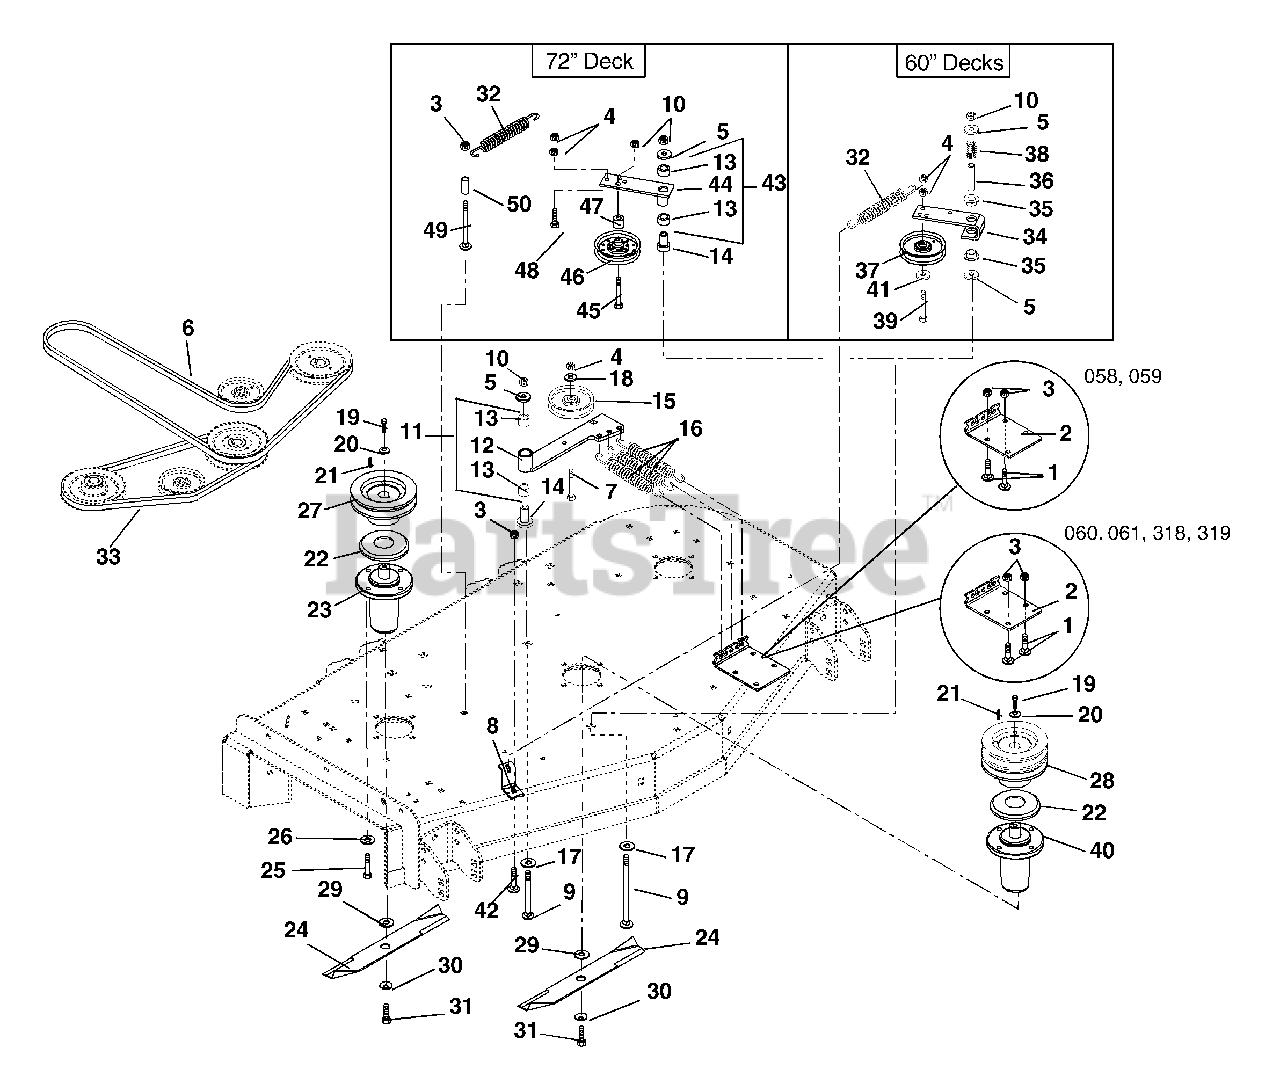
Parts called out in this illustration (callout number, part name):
1	Bolt, Round Head Square Neck .38-16 x .75 Grade 5
2	Bracket, Spring
3	Nut, Locking Top Flange .38-16 (058, 060, 318, 319)
3	Nut, Locking Top Flange .38-16 (059, 061)
4	Nut, Locking Center .38-16
5	Washer, Flat Steel .531 x 1.25 x .10 (058, 060, 318, 319)
5	Washer, Flat Steel .531 x 1.25 x .10 (059, 061)
6	V-BELT, HB-WRAPPED (058, 060, 318, 319)
6	V-Belt, B-Section 58.25 x .625 (059, 061)
7	Bolt-Round Head Square Neck .38-16 x 2.75 Grade 5
8	Anchor, Spring
9	Bolt, Round Head Square Neck .50-13 x 3.50 Grade 5
10	Nut, Locking Top Flange .50-13 (058, 060, 318, 319)
10	Nut, Locking Top Flange .50-13 (059, 061)
11	Assembly-Deck Idler Pivot Arm (Contains Items 12 & 13)
12	Weldment, Deck Idler Pivot Arm
13	Bearing, 1.00 x 1.12 x .75
14	Bearing, Pedestal Powdered Metal (058, 060, 318, 319)
14	Bearing, Pedestal Powdered Metal (059, 061)
15	Idler, Flat 4.00 x .38 (2.32W)
16	Spring, Extension
17	Washer, Flat Steel .755 x 1.375 x .062
18	Washer, Flat Steel .375 x 1.125 x .065
19	Bolt, Hex .38-16 x 1.00 Grade 8
20	Washer, Cupped Serrated .375
21	Key, Square .25 x .25 x 1.00
22	Slinger, Dust
23	Assembly, Maintenance Free Spindle
24	Blade 60" Mower CE (318, 319)
24	Blade, Mower 60" Mulch (058, 060, 318, 319)
24	Blade, Mower-72" (24.50" LG) (059, 061)
24	Blade, Mower (058, 060)
24	Blade, Mower 72" Mulch (059, 061)
25	Bolt, Hex .38-16 x 1.00 Grade 5
26	Washer, Locking .38 x .094 Regular
27	Weldment, Spindle Sheave 6.00 (058, 060, 318, 319)
27	Weldment, Spindle Sheave (059, 061)
28	Sheave, Double (6.25) (058, 060, 318, 319)
28	Sheave, Double (7.25) (059, 061)
29	Washer, Flat .64 x 1.81 x .25
30	Washer, Bellville .63 x 1.625 x .14
31	Bolt, Hex .62-18 x 1.75 Grade 8
32	Spring, Extension (058, 060, 318, 319)
33	V-Belt B-Section 23.94 x .625 (058, 060, 318, 319)
33	V-Belt 5L-Section 49.97 x .672 (059, 061)
34	Arm, Idler Pivot (058, 060, 318, 319)
35	Bushing, Flange .762 x 1.00 x .58 x 1.48 Nylon (058, 060, 318, 319)
36	Spacer .56 x .75 x 2.44 Steel (058, 060, 318, 319)
37	V-Idler, 4.00 x .38 (058, 060, 318, 319)
38	Spring, Compression .085 x .80 x 1.00 (058, 060, 318, 319)
39	Bolt, Hex .38-16 x 2.25 Grade 5 (058, 060, 318, 319)
40	Spindle Assembly (Center)
41	Washer, Flat Steel .406 x .812 x .05 (058, 060, 318, 319)
42	Bolt, Round Head Square Neck .38-16 x 1.00 Grade 5
43	Assembly, Idler Arm Guard Drive
44	Weldment, Idler Arm Ground Drive (059, 061)
45	Bolt, Hex .38-16 x 6.00 Grade 5 (059, 061)
46	Idler, Flat Pulley 6.75 xz .51 (059, 061)
47	Spacer .513 x .748 x .62 (059, 061)
48	Bolt, Hex .38-16 x 1.25 Grade 5 (059, 061)
49	Bolt, Round Head Square Neck .38-16 x 2.75 Grade 5 (059, 061)
50	Spacer .38 x .625 x 1.50 (059, 061)
